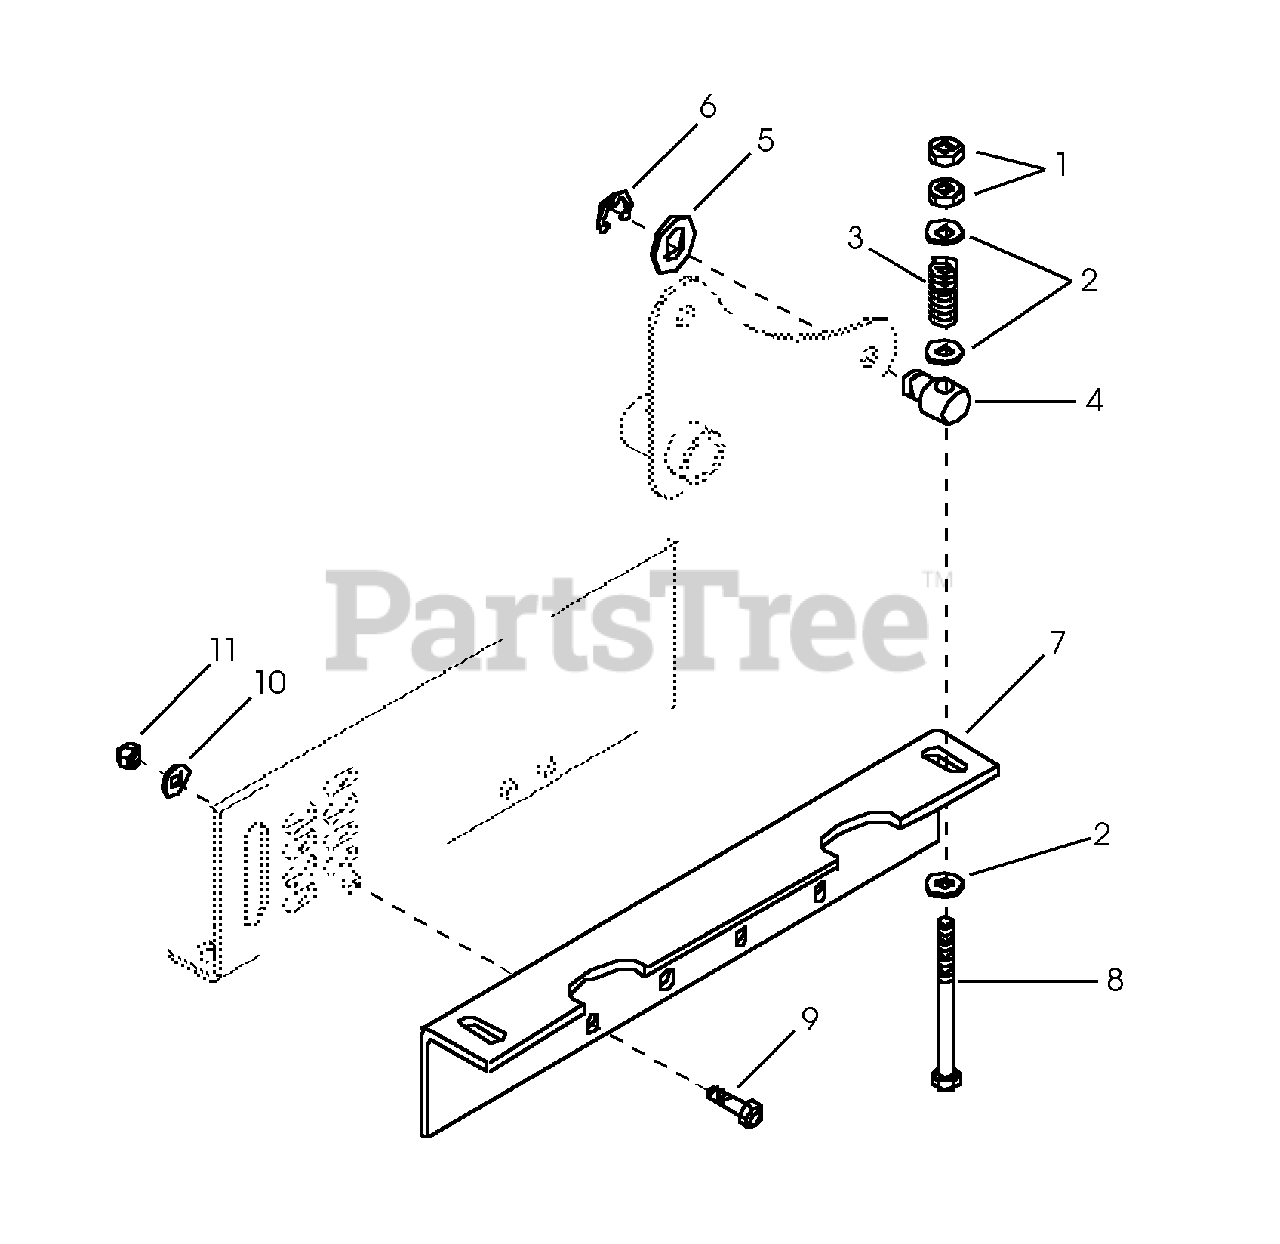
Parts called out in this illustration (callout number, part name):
1	Nut-Jam .50-13
2	Washer-Flat-Steel .52 x .827 x .062
3	Spring-Compression .125 x .78 x 1.00
4	Pivot, Mower Lift
5	Washer-Flat-Steel .656 x 1.31 x .095
6	Ring-Retaining-External .750 x .050
7	Lift Bracket
8	Bolt-Hex .50-13 x 6.50 Grade 5
9	Bolt-Hex .38-16 x 1.25 Grade 5
10	Washer-Flat-Steel .406 x .812 x .065
11	Nut-Locking-Nylon .375-16
